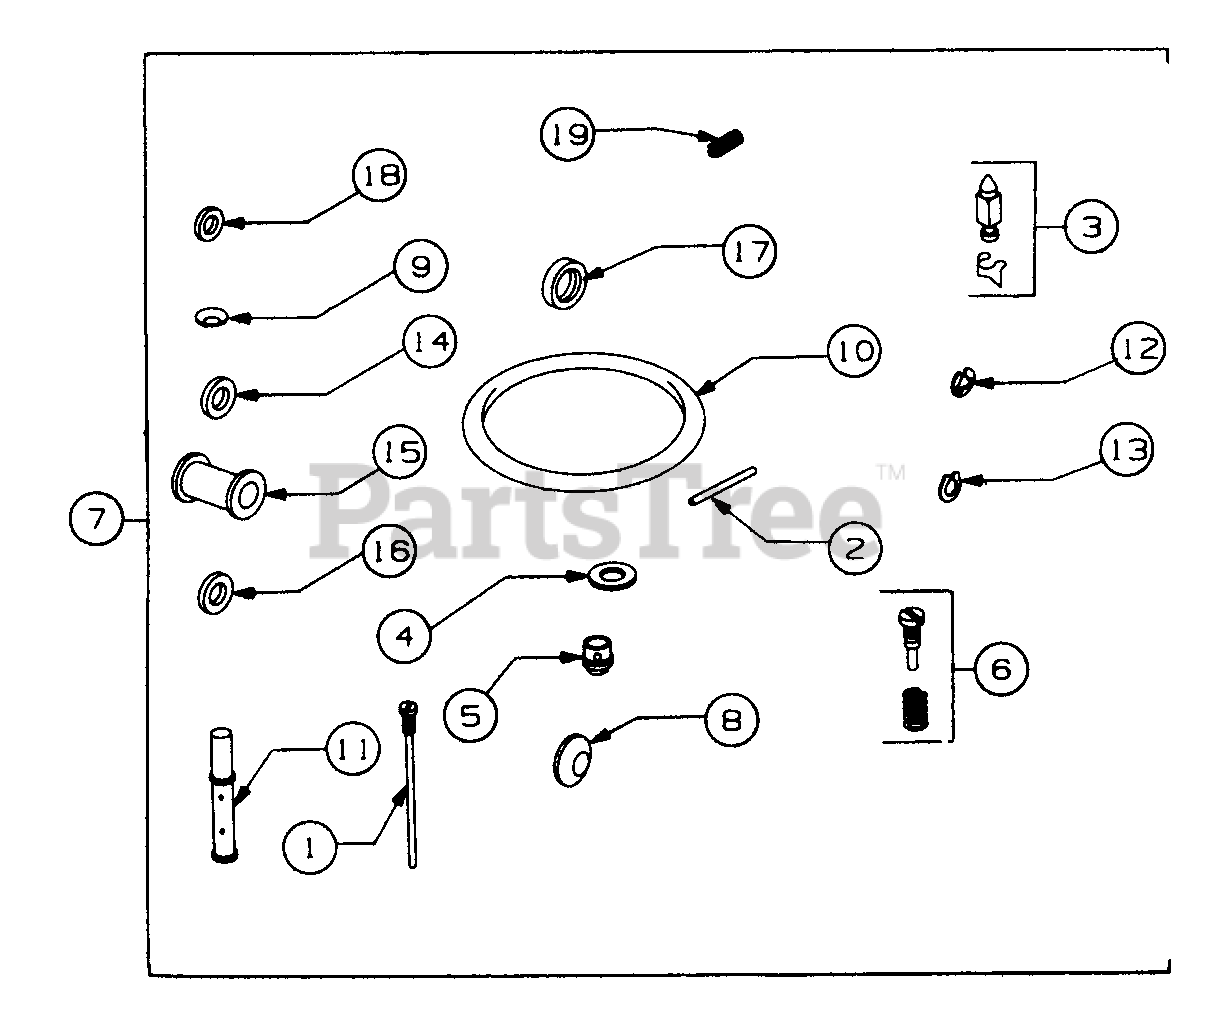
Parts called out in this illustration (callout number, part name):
1	Nozzle, Carburetor
2	Pin, Float Hinge
3	Valve, Fuel Inlet
4	Gasket, Sealing (Sold in kit only)
6	Valve Assy, Carburetor Idle
7	Overhaul Kit, Carburetor
8	Plug, Welch
9	Plug, Welch
10	Gasket, Bowl Mtg (Sold in kit only)
11	Nozzle (Includes Ref No. 5)
12	Retainer, Choke Shaft
13	Retainer, Throttle Shaft
14	Collar, Throttle
15	Collar, Throttle
16	Collar, Choke
17	Seal, Throttle Shaft
18	Seal, Choke Shaft
19	Ball, Choke Locator
